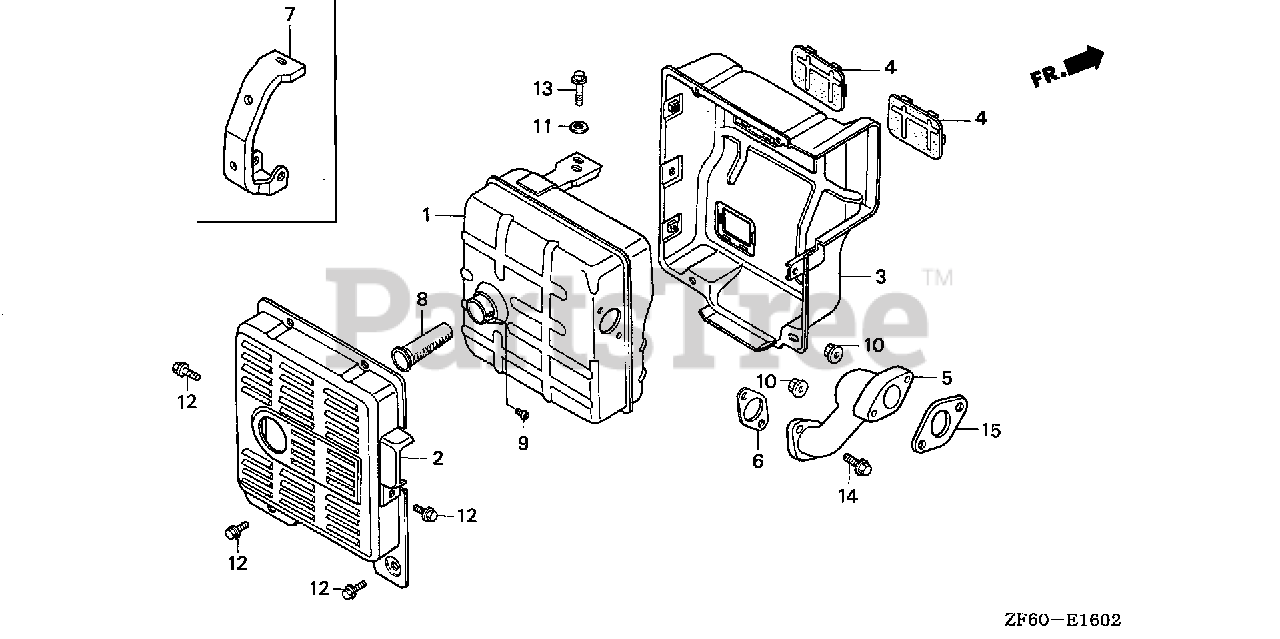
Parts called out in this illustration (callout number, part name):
1	MUFFLER (TSURUMI)
3	PROTECTOR, MUFFLER (INNER)
4	SEAL, MUFFLER PROTECTOR
6	GASKET, EX. PIPE
8	ARRESTER, SPARK
9	SCREW, TAPPING (4X8)
10	NUT, FLANGE (8MM)
14	BOLT, FLANGE (8X20)
15	GASKET, EX. PIPE
